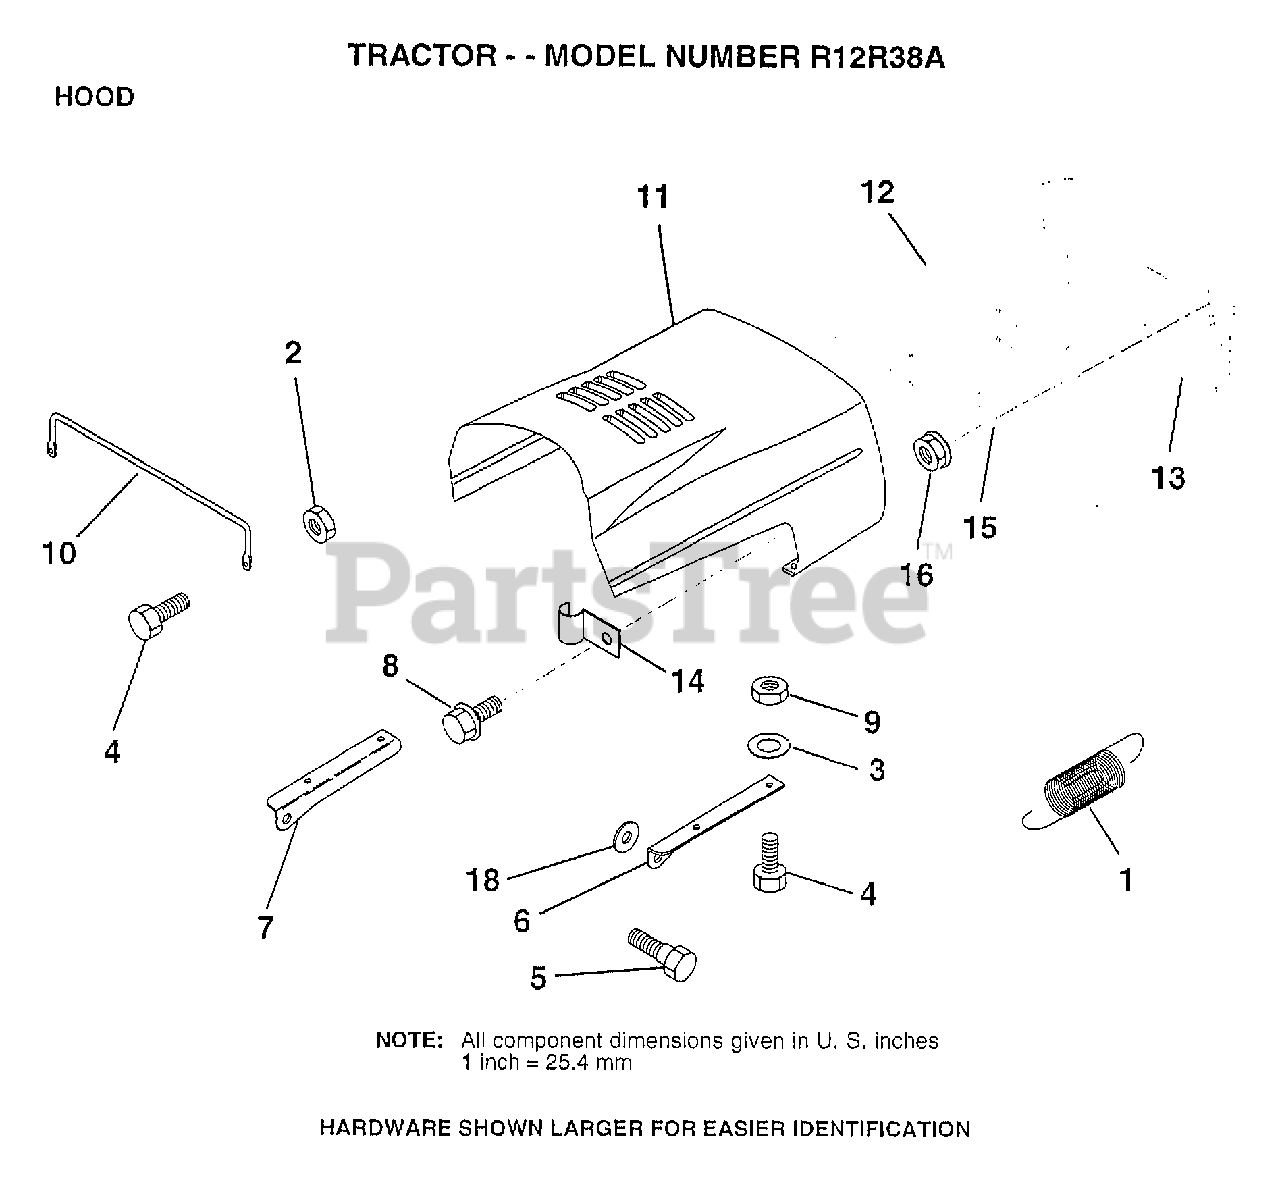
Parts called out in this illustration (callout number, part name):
1	EXT SPRING
2	NUT HXKEP 1/4X20
3	WASHER
5	BOLT.SHLD.5/16-18
6	BRKT HOOD RH
7	BRKT HOOD LH
8	SCREW SLTD HXHD
9	NUT
10	"BRACE,HOOD"
11	HOOD
13	GRILL (BLACK)
16	NUT
18	WASHER
